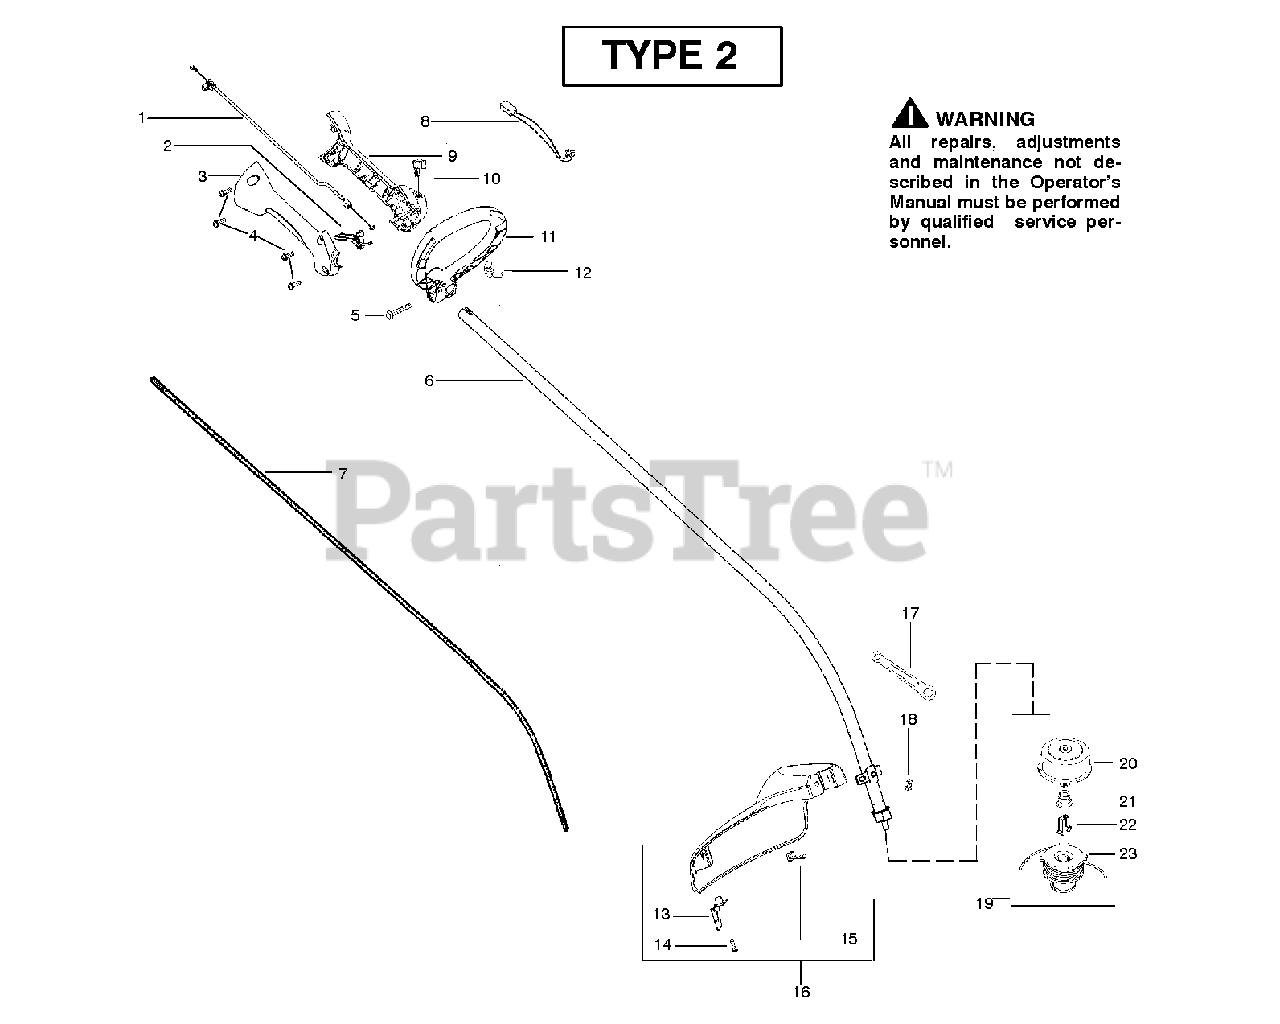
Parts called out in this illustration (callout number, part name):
1	ASSY THROTTLE CABLE
3	HSG THROTTLE RH
5	BOLT\-1/4-20X1-1/2
6	DRIVE SHAFT ASSY
7	DRIVE SHAFT
8	WIRE ASSY
11	ASSY ASSIST HANDLE
12	WINGNUT, TYPE 2
14	SCREW - THROTTLE HOUSING
15	BOLT, TYPE 2
20	TNG VI HUB ASSY 5/16" RH
22	RETAINER
23	WOUND SPOOL ASSY .080 x 2
